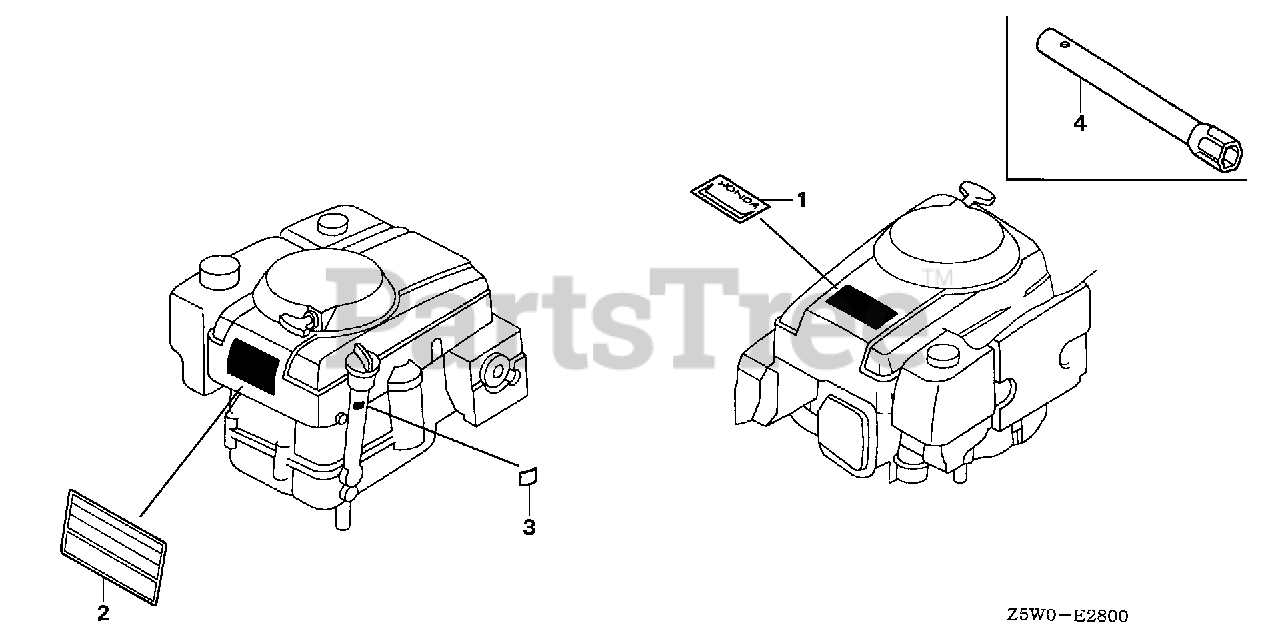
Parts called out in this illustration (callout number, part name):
1	EMBLEM, TOP COVER (GXV390)
2	MARK, OPERATOR CAUTION (ENGLISH)(MADE IN THAI)
2	MARK, OPERATOR CAUTION (PICTOGRAPH)(MADE IN THAI)
3	MARK, TYPE (DA33)
4	WRENCH, BOX (P21)
